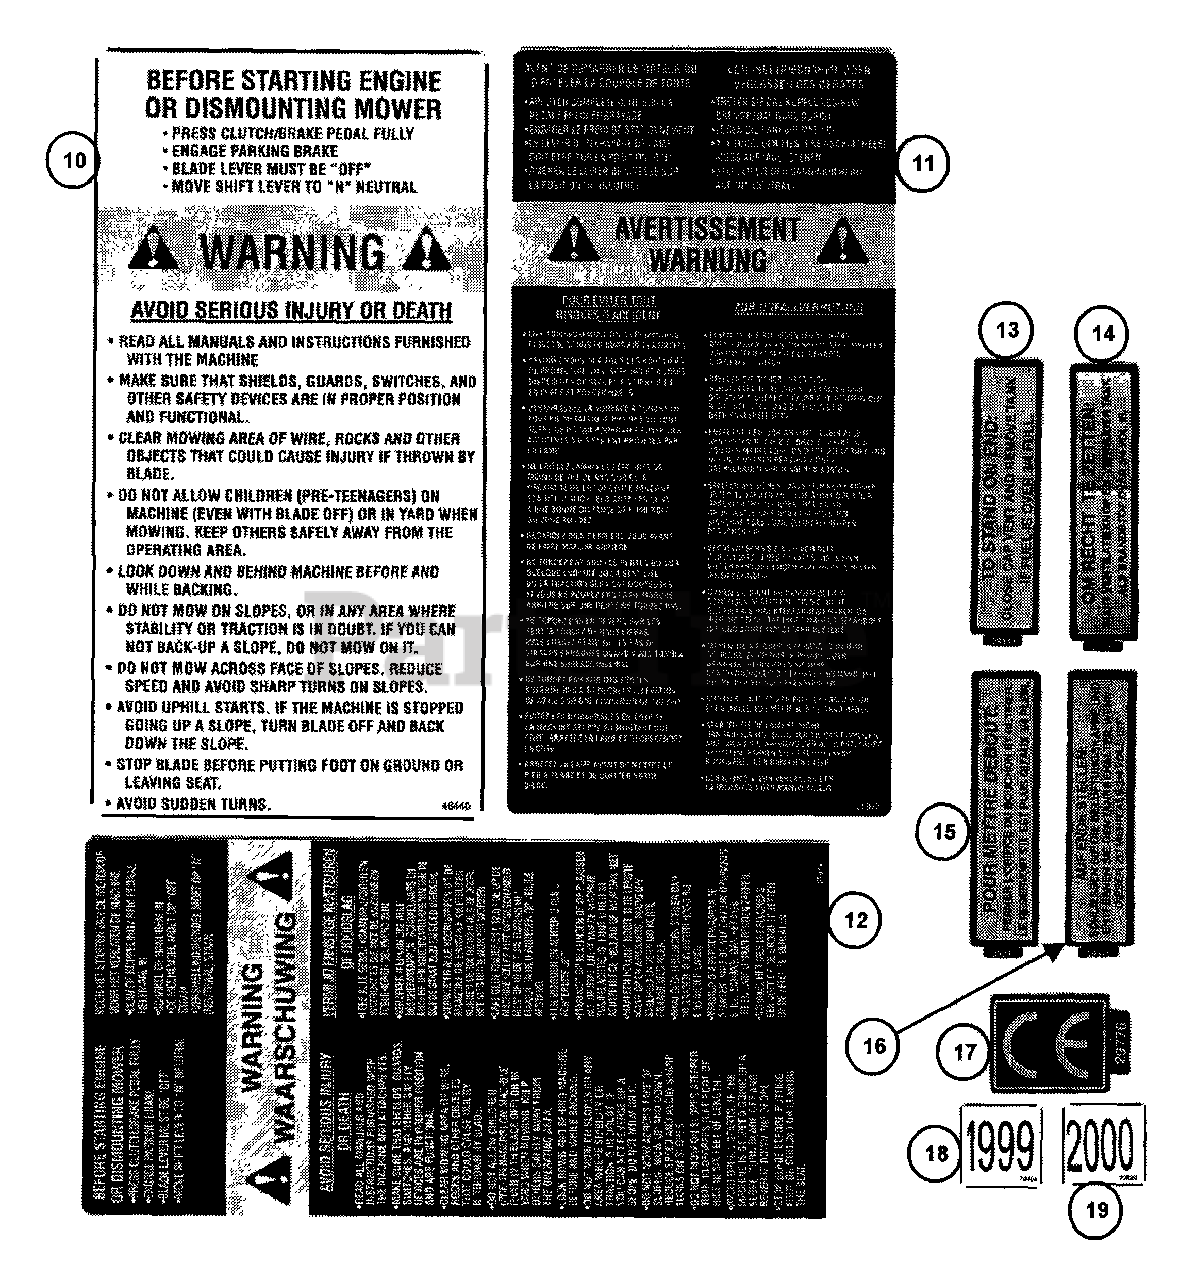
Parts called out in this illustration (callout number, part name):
10	DECAL, Safety Instructions
11	DECAL, Safety Instructions (French/German)
12	DECAL, Safety Instructions (English/Dutch)
13	DECAL, Caution Fuel Leakage (English)
14	DECAL, Caution Fuel (Dutch)
15	DECAL, Caution Fuel (French)
16	DECAL, Caution Fuel (Ger.)
17	DECAL, Euro Community (CE)
18	DECAL, 1999 Year of Manufacture
19	DECAL, 2000 Year of Mfr.
